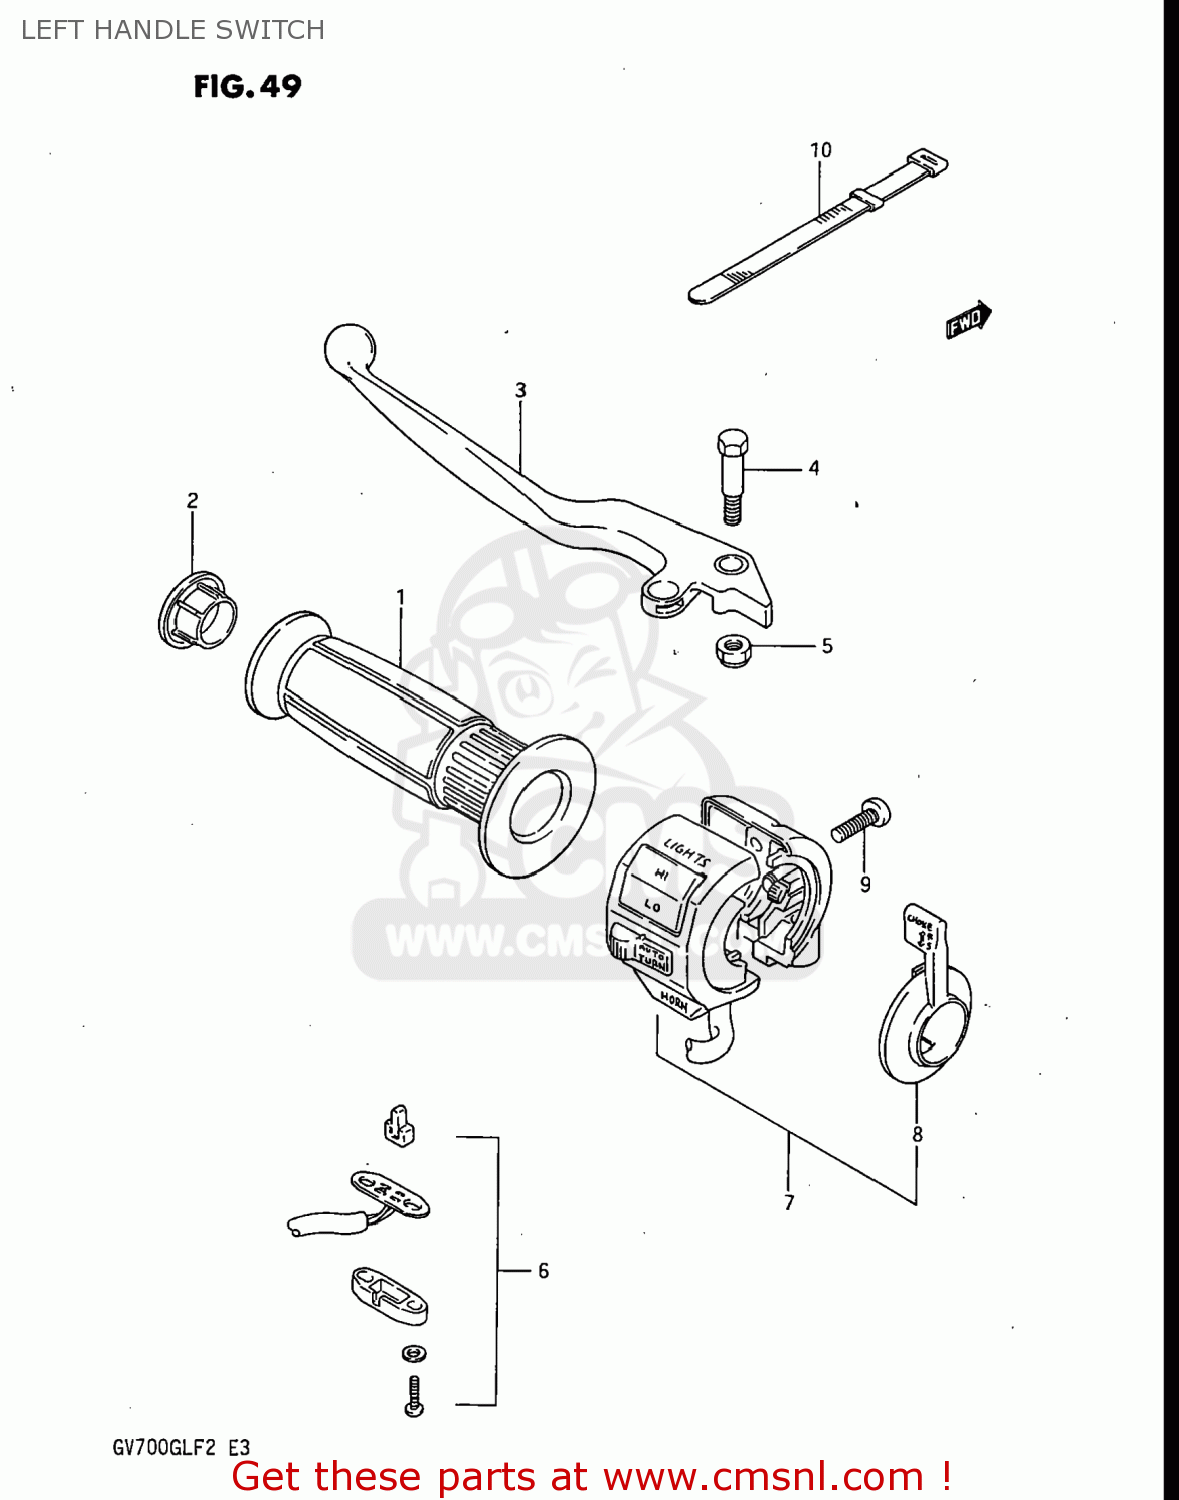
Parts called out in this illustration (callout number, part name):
1	GRIP,LEFT
2	CAP,GRIP END
3	LEVER,CLUTCH (BLACK)
4	BOLT,LEVER
5	NUT
6	SWITCH ASSEMBLY,CLUTCH
7	SWITCH ASSEMBLY,HANDLE,LEFT
8	LEVER,CHOKE
9	SCREW 5X20
10	CLAMP(L:120)
